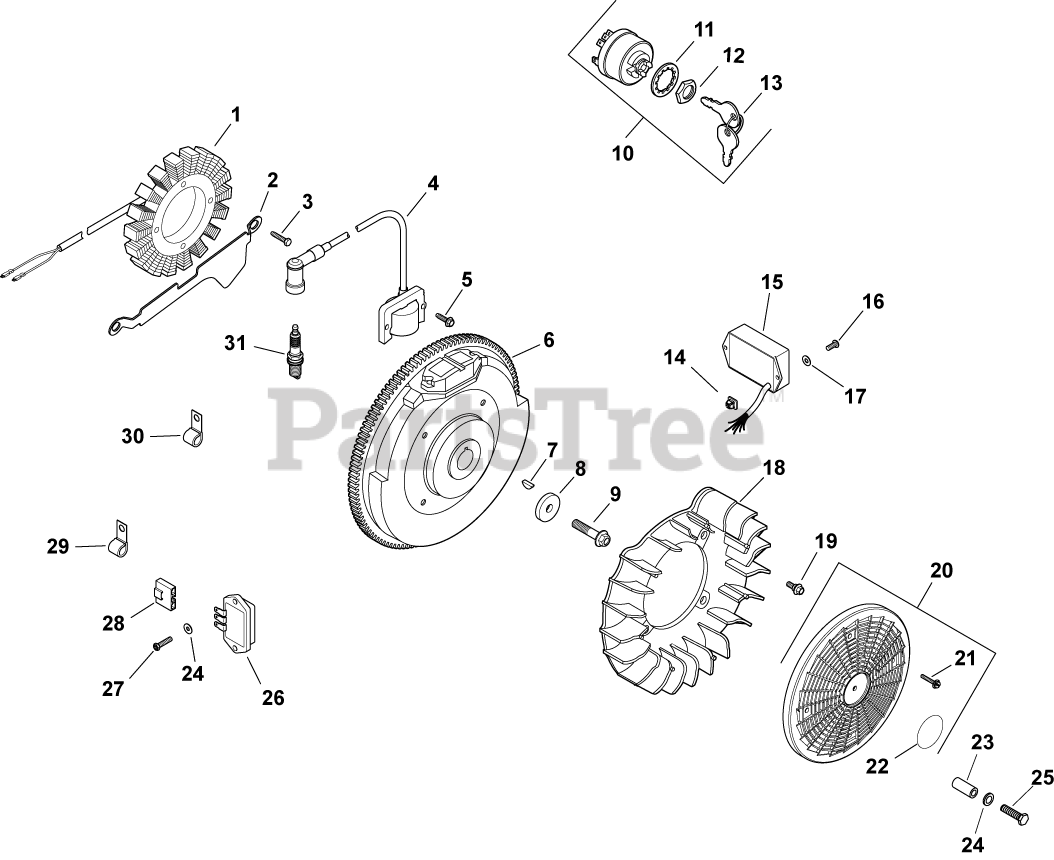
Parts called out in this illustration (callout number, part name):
1	KIT, 15 / 20 AMP STATOR
2	BRACKET, STATOR WIRE
3	SCREW, M5X0.8X25 - (#25086402S)
5	SCREW, SKT THD FRM M5X0.8X25
6	FLYWHEEL ASSEMBLY - USE 24 025 14-S
7	KEY, 3/16" X 5/8"
8	WASHER, FLAT 13/32"
9	SCREW, FLG M10X1.5X45 - (#25086361S)
10	SWITCH ASSY, KEY (KM)-USE 25 099 32-S
11	WASHER, INTERNAL TOOTH
12	NUT, KEY SWITCH
13	KEY, SET -USE 48 340 01-S
14	NUT, PLASTIC
15	MODULE, SPEED ADVANCE-DISCONTINUED SEE PB265
16	SCREW, PHL HD #11-16X1/2"
17	WASHER, FLAT 1/4" (O.D. 1/2")
18	FAN (WITH HOLE)-USE 24 157 16-S
19	BOLT, SHOULDER
20	KIT, GRASS SCREEN
21	SCREW, WSH HD TAP #8-18X1/2"
22	DECAL, GRASS SCREEN USE 24 113 499-S
23	SPACER - DISCONTINUED
24	WASHER, FLAT 3/16"
25	SCREW, SLT HD CAP M4X0.7X25
27	SCREW, PHL HD #11-16X7/8"
28	CONNECTOR, BODY (KM)-USE 25 155 41-S
29	CLIP, CABLE
30	CLIP, CABLE - USE 24 154 10-S
31	PLUG, SPARK (STD)
